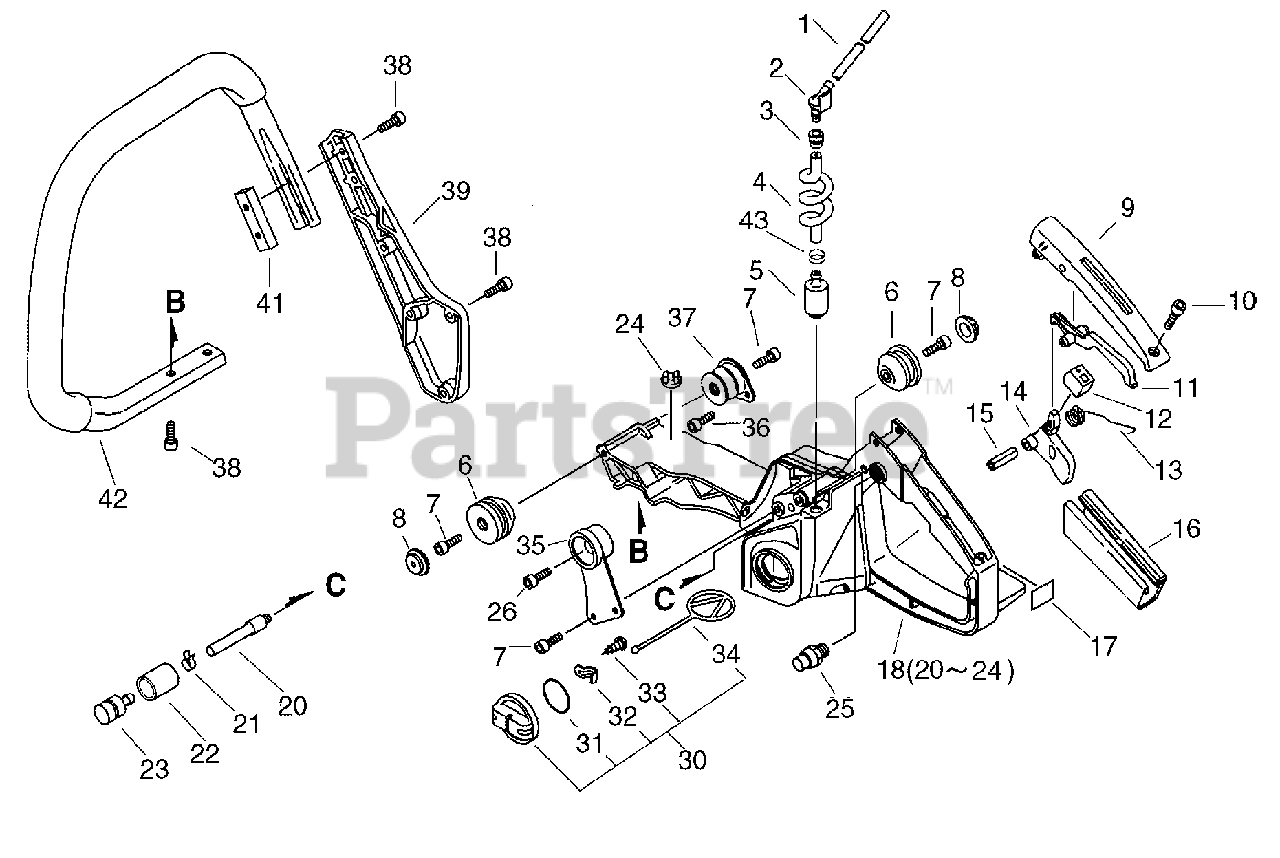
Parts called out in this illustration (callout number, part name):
1	PIPE, FUEL 3×6×120 BLACK
2	CONNECTOR, PIPE
3	GROMMET
4	PIPE, FUEL
5	FILTER, FUEL
7	BOLT 5×14
8	CAP, CUSHION
9	COVER, HANDLE
10	BOLT 4×14
11	CONTROL, THROTTLE
12	CUSHION, THROTTLE
13	SPRING, THROTTLE RETURN
14	TRIGGER, THROTTLE - BLACK
15	PIN, SPRING Ø5×25 MM
16	GRIP, HANDLE
17	LABEL, STOP
18	REAR HANDLE ASSY - ORANGE
20	PIPE 3×5×90
22	HOLDER, VENT
23	VENT ASSY
25	LATCH, THROTTLE
26	BOLT 5×20
30	CAP ASSY, FUEL
31	O-RING 29
32	RETAINER, CONNECTOR
33	SCREW, TAPPING 3×8
34	CONNECTOR, CAP L= 60 MM
36	BOLT 4×10
38	BOLT 5×20
39	BRACKET, FRONT HANDLE
42	HANDLE, FRONT
43	CLIP Ø6.5 MM
